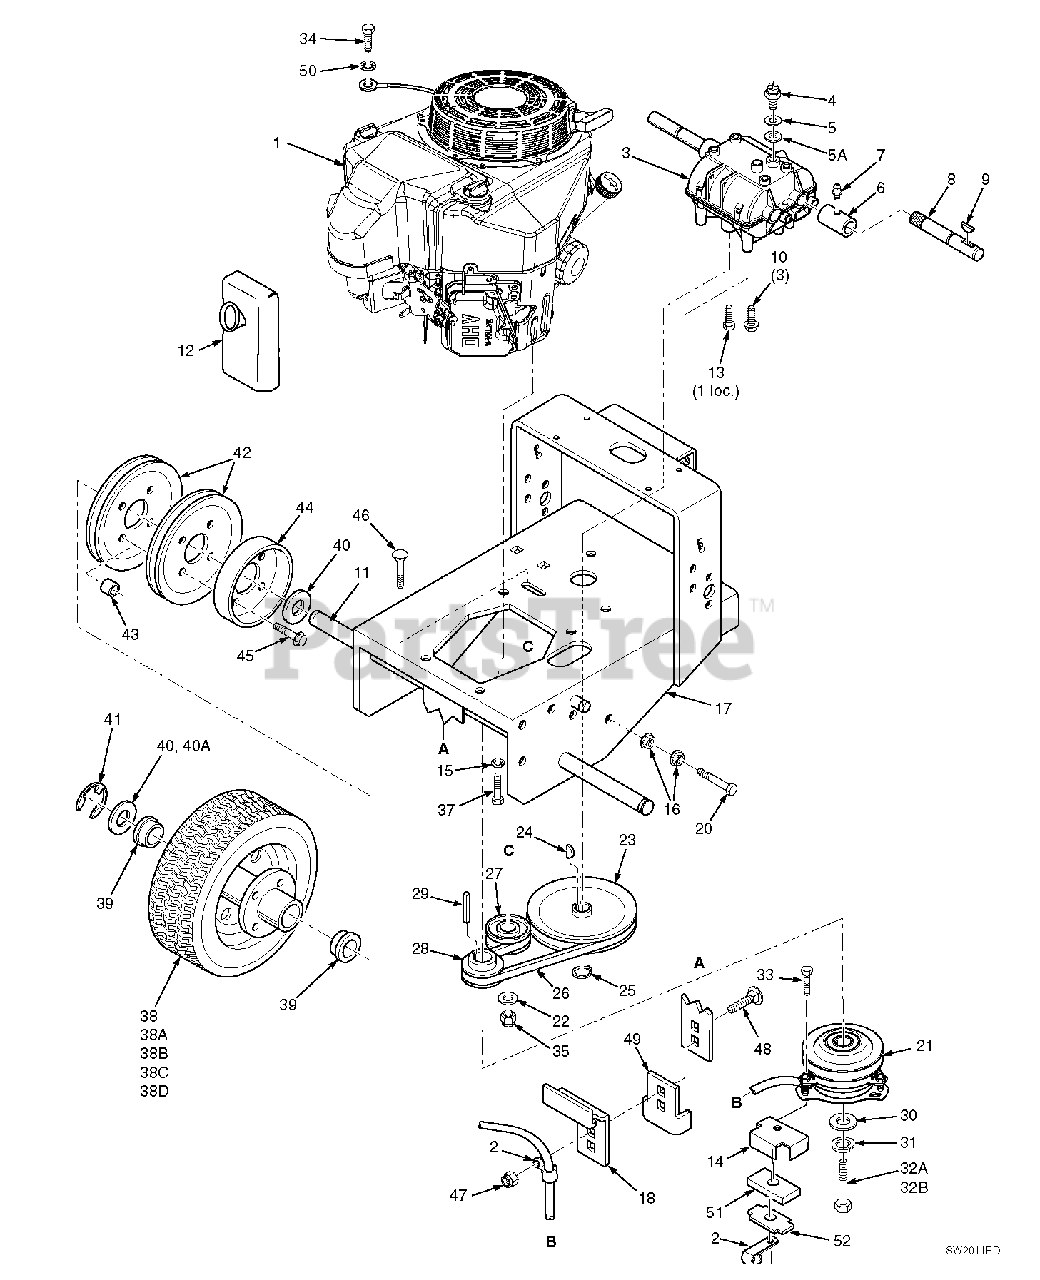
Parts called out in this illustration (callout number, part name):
1	Engine
2	Cable Clamp
3	Transmission, 5-speed
4	Neutral Safety Switch
5	Fibre Washer, thin
5A	Fibre Washer, thick
6	Coupler, Jackshaft
7	Grease Fitting, straight 1/4-28
8	Jackshaft
9	Key, Hi-Pro #9
10	Bolt, 5/16-18 X 3/4" Hex Head
11	Wheel Axle
12	Muffler
13	Bolt, 5/16-18 X 3/4" Hex Head
14	Backing Plate
15	Lock Wshr. 3/8"
16	Nut, 3/8-16 Serrated Flange
17	Engine Deck
18	Plate, Clutch Bracket
19	Nut, 5/16-18 Serrated Flange
20	Bolt, 3/8-16 x 3-3/4" Hex Head
21	Electric Clutch (Ogura)
22	Washer, 3/8
23	Pulley, Transmission Input
24	Key, Woodruff #9
25	Retaining Ring, 5/8" Ext, Basic
26	Belt, Transmission Drive
27	Idler Pulley, Transmission
28	Pulley, Traction Drive
29	Key, 1/4 x 1/4 x 3/4"
30	Flat Washer, 7/16" Special
31	Lock Washer, 7/16"
32A	Bolt, 7/16-20 x 2-1/2" Hex Head
32B	Cpsrw, M10-1.5 x55 Metric Hex Hd
33	Bolt, 5/16-18 x 1-3/4" Hex Head
34	Bolt, M8-1.25 x 16
35	Nut, 3/8-16 Elastic Stop
36	Flat Washer, 5/16"
37	Bolt, Hex Head 3/8-16 x 1-1/4"
38	Wheel Assembly
38A	Tire, 13 x 6.50-6, 2-ply
38B	Rim & Bearing Assembly
38C	Tire, 13 x 5.00-6 2-ply
38D	Rim Assembly
39	Wheel Bearing
40	Washer, 1-1/16 x 1-3/4 x 12 ga
40A	Washer, 1-1/16 x 1-1/2 x 18 ga
41	Retaining Ring, 1" Ext.- "E"
42	Pulley, Wheel Drive
43	Spacer, Wheel Pulley
44	Brake Drum
45	Bolt, 5/16-18 x 1-1/2" Serrated Flange
46	Bolt, 3/8-16 x 2" Carriage
47	Nut, 5/16-18 Elastic Stop
48	Bolt, 5/16-18 x 1" Carriage
49	Anti Rotation Bracket
50	Lock Washer External Tooth
51	Rubber Pad, Clutch Stop
52	Plate, Backing
